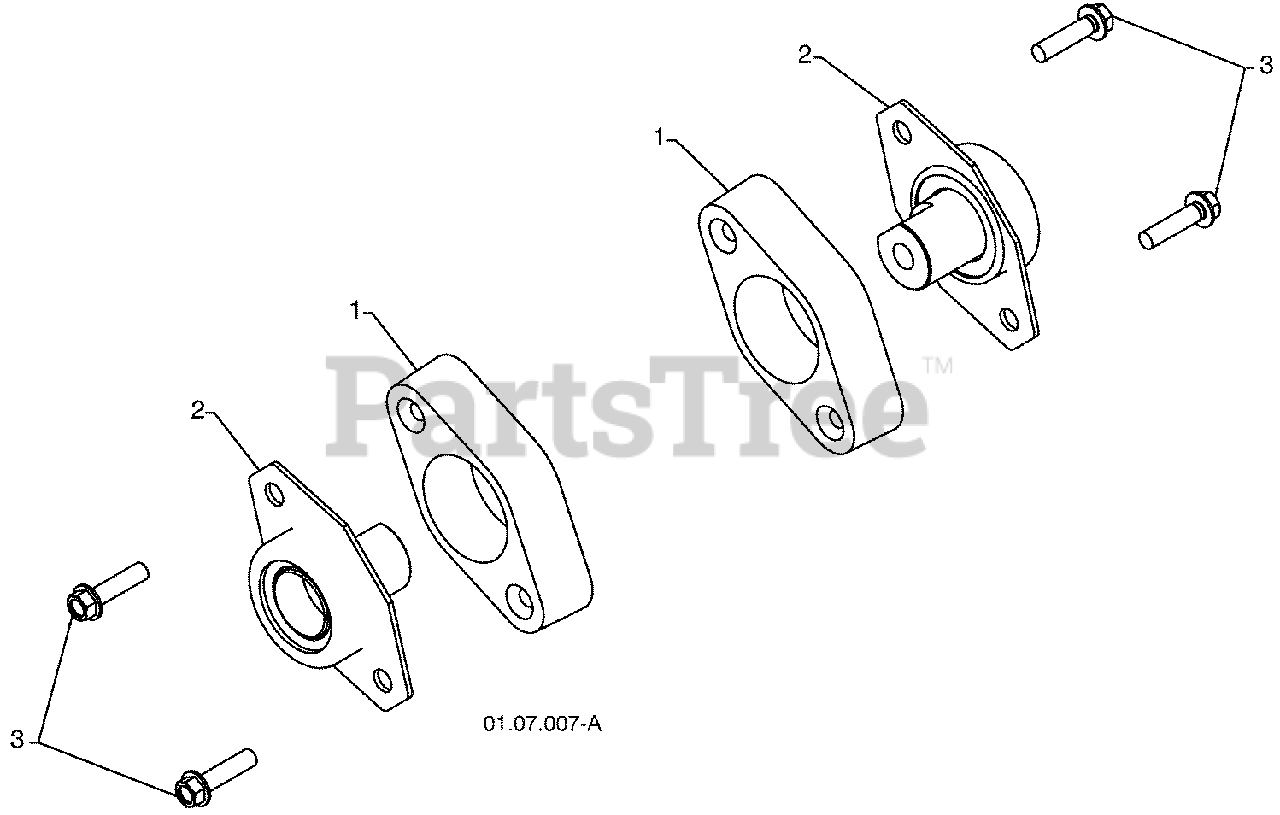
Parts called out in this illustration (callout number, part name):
1	PLASTIC RETAINER
2	AUGER BALL BEARING
3	SCREW 5/16-18 X 1.00
